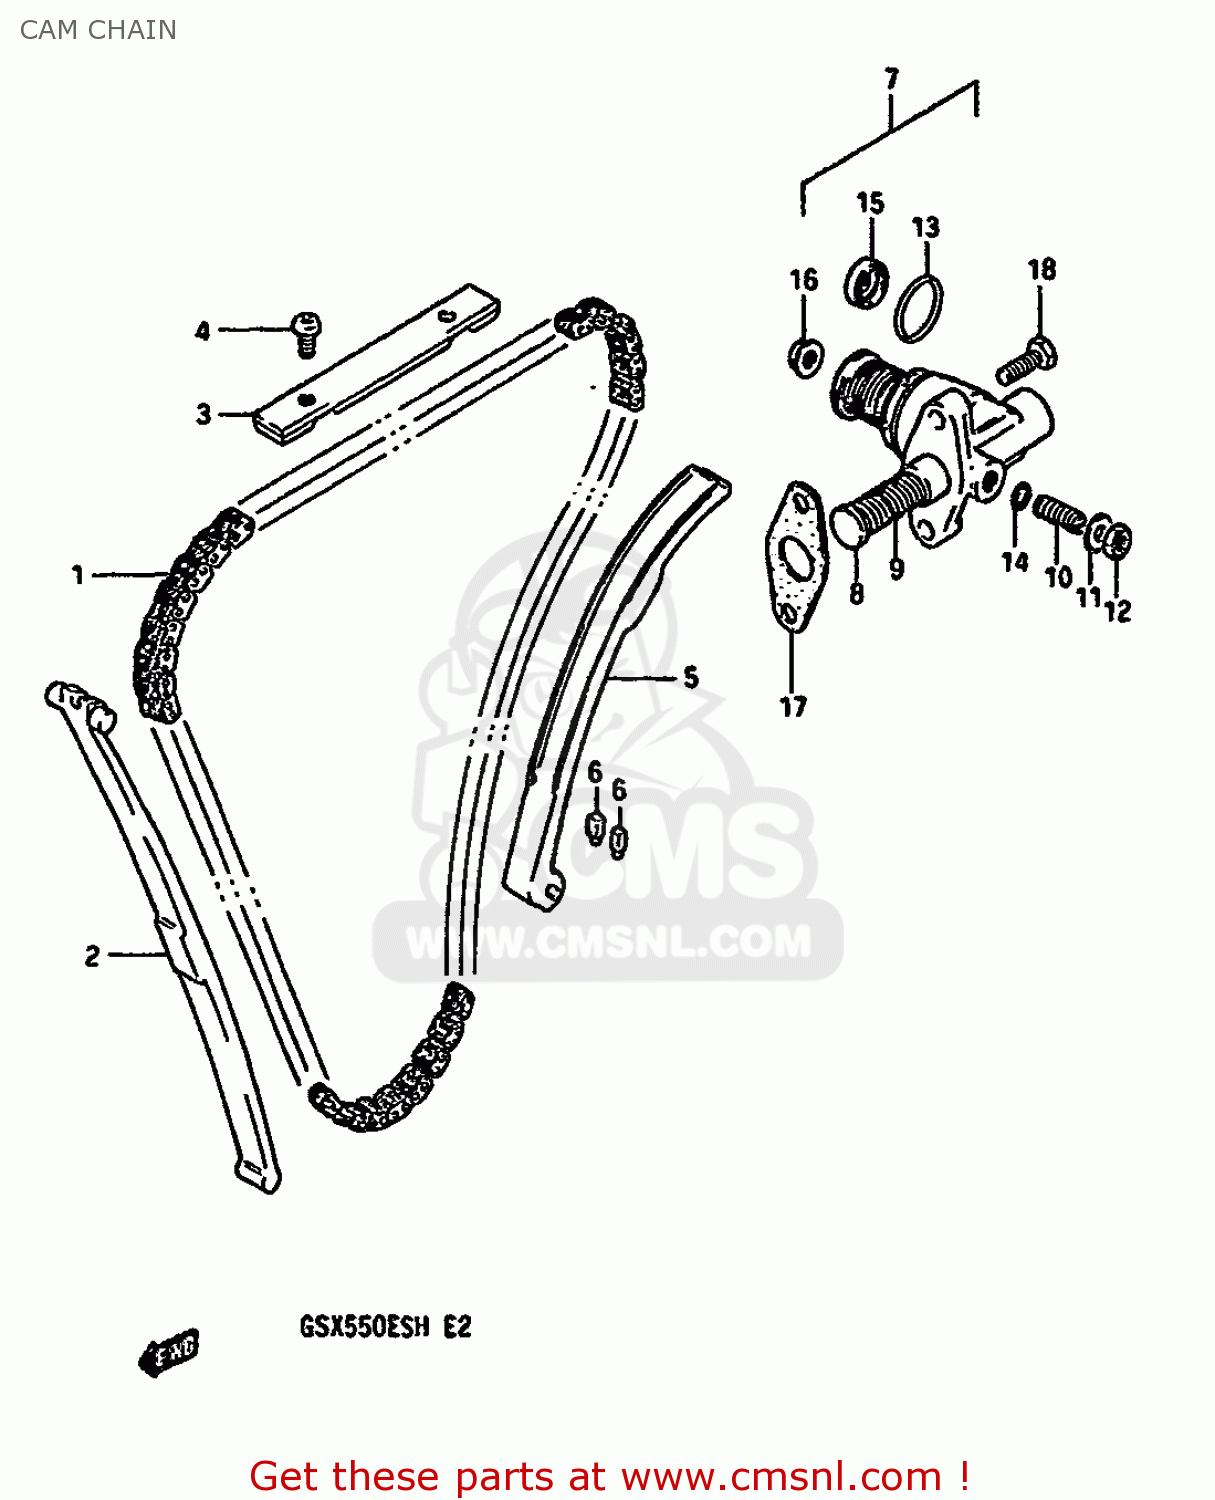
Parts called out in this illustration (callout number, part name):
1	CHAIN,CAMSHAFT DRIVE
2	GUIDE,CAM CHAIN NO.1
3	GUIDE,CAM CHAIN NO.2
4	SCREW
5	TENSIONER,CAM CHAIN
6	CUSHION,CAM CHAIN TENSIONER
7	ADJUSTER ASSY,TENSIONER
8	ROD,PUSH
9	SPRING
10	SCREW,TENSIONER ADJUST
11	WASHER
12	NUT
13	O RING(D:2.4,ID:20.8)
14	O RING(D:1.9,ID:5.7)
15	SEAL,OIL(10X16X4)
16	NUT 6MM
17	GASKET,TENSIONER ADJUSTER (MCA)
18	SCREW
